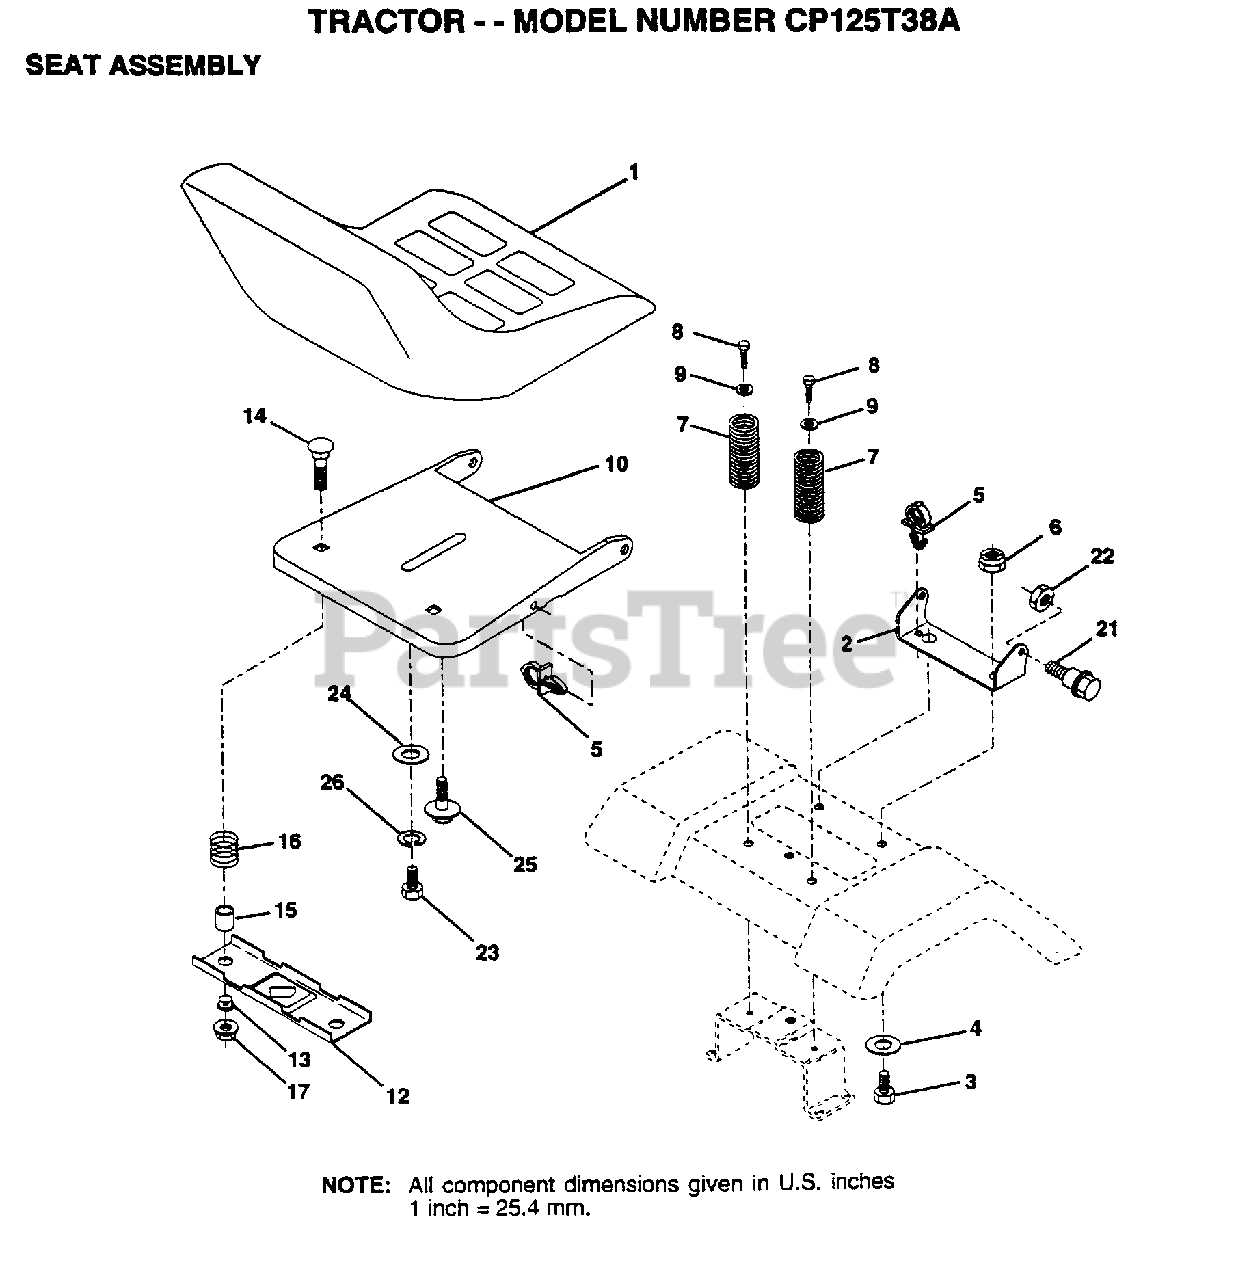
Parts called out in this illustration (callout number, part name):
2	BRACKET PVT SEAT
3	BOLT
4	WASHER PM
5	CLIP.PUSH-IN.HING
6	NUT
7	SPRING COMPRESSIO
8	SCREW GTV
9	WASHER
12	SPACER SPLIT
13	BUSHING
15	SPLIT SPACER
16	SPRING
21	BOLT.SHLD.5/16-18
22	NUT
23	BOLT
24	WASHER
25	"BOLT,SHOULDER"
26	LOCKWASHER
